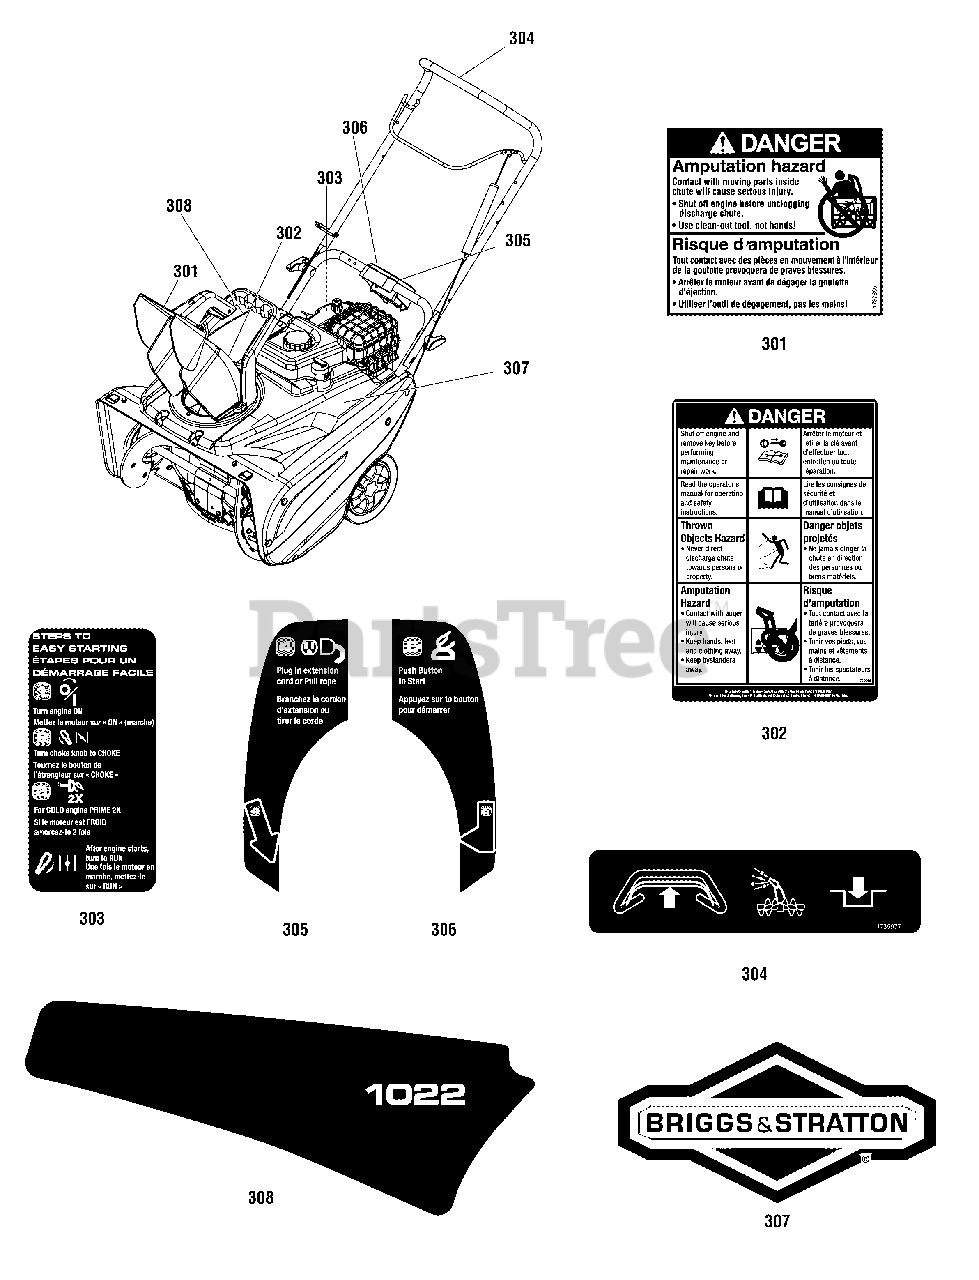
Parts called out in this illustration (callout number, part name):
301	*DECAL, Danger Chute FR/ENG
302	*DECAL, Chute FR/EN
303	*DECAL, Step 1-2-3
304	*DECAL, Bail Engagement
305	*DECAL, 4 Start, FR-EN
306	*DECAL, 5 Start, FR-EN
307	*DECAL, Briggs Brand
308	*DECAL, Briggs Model 1022E
308	*DECAL, Briggs Model 1022
0340	KIT-DECAL SHEET, Electric Start
0340	KIT-DECAL SHEET, Recoil Start
